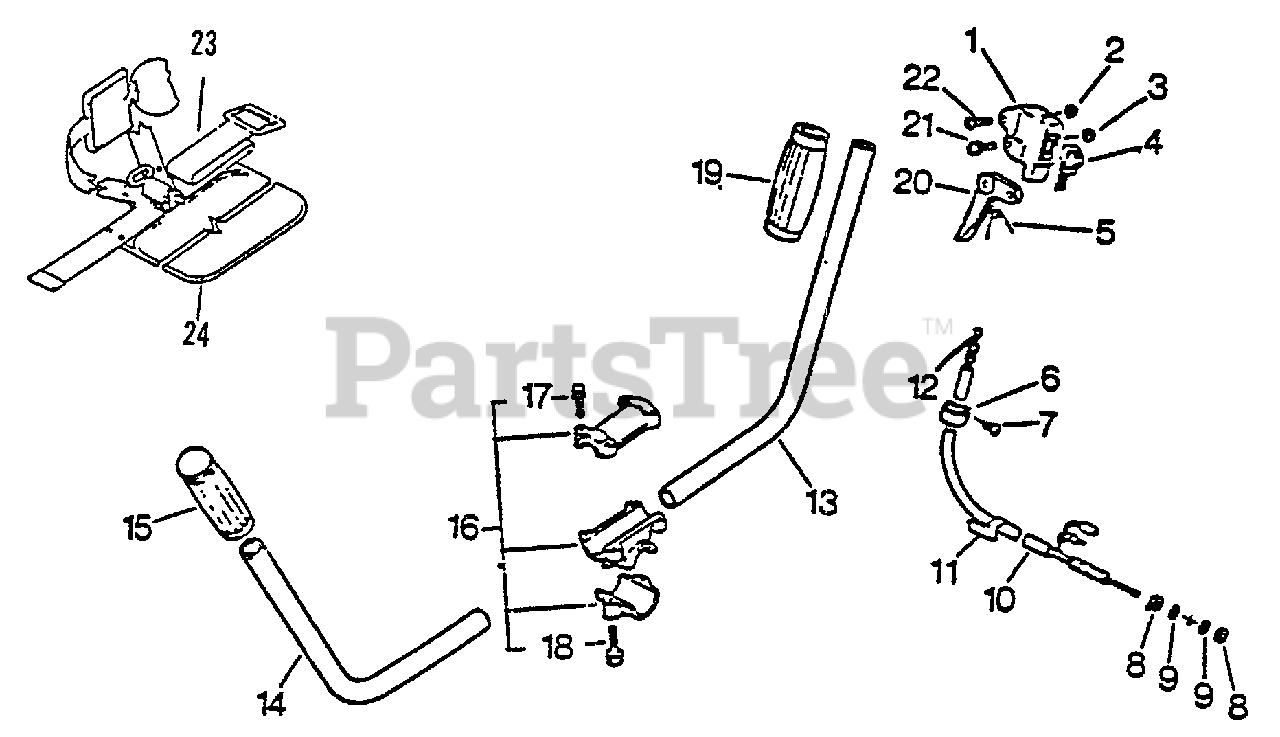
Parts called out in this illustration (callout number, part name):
1	BRACKET, THROTTLE
2	LOCKNUT - 5
4	IGNITION SWITCH ASSY
5	SPRING, TRIGGER
7	SCREW - 5X10
8	LOCKNUT - 6
9	WASHER - 6
10	TUBE - VINYL
12	CABLE, THROTTLE
14	HANDLE, FRONT - LEFT
15	GRIP, HANDLE - LEFT
16	HANDLE BRACKET KIT
17	BOLT - 5X25
18	BOLT - 6X30
19	GRIP, HANDLE
20	TRIGGER, THROTTLE
21	SCREW - 5X25
22	SCREW - 5X30
23	CUSHION
24	SHOULDER STRAP ASSY
